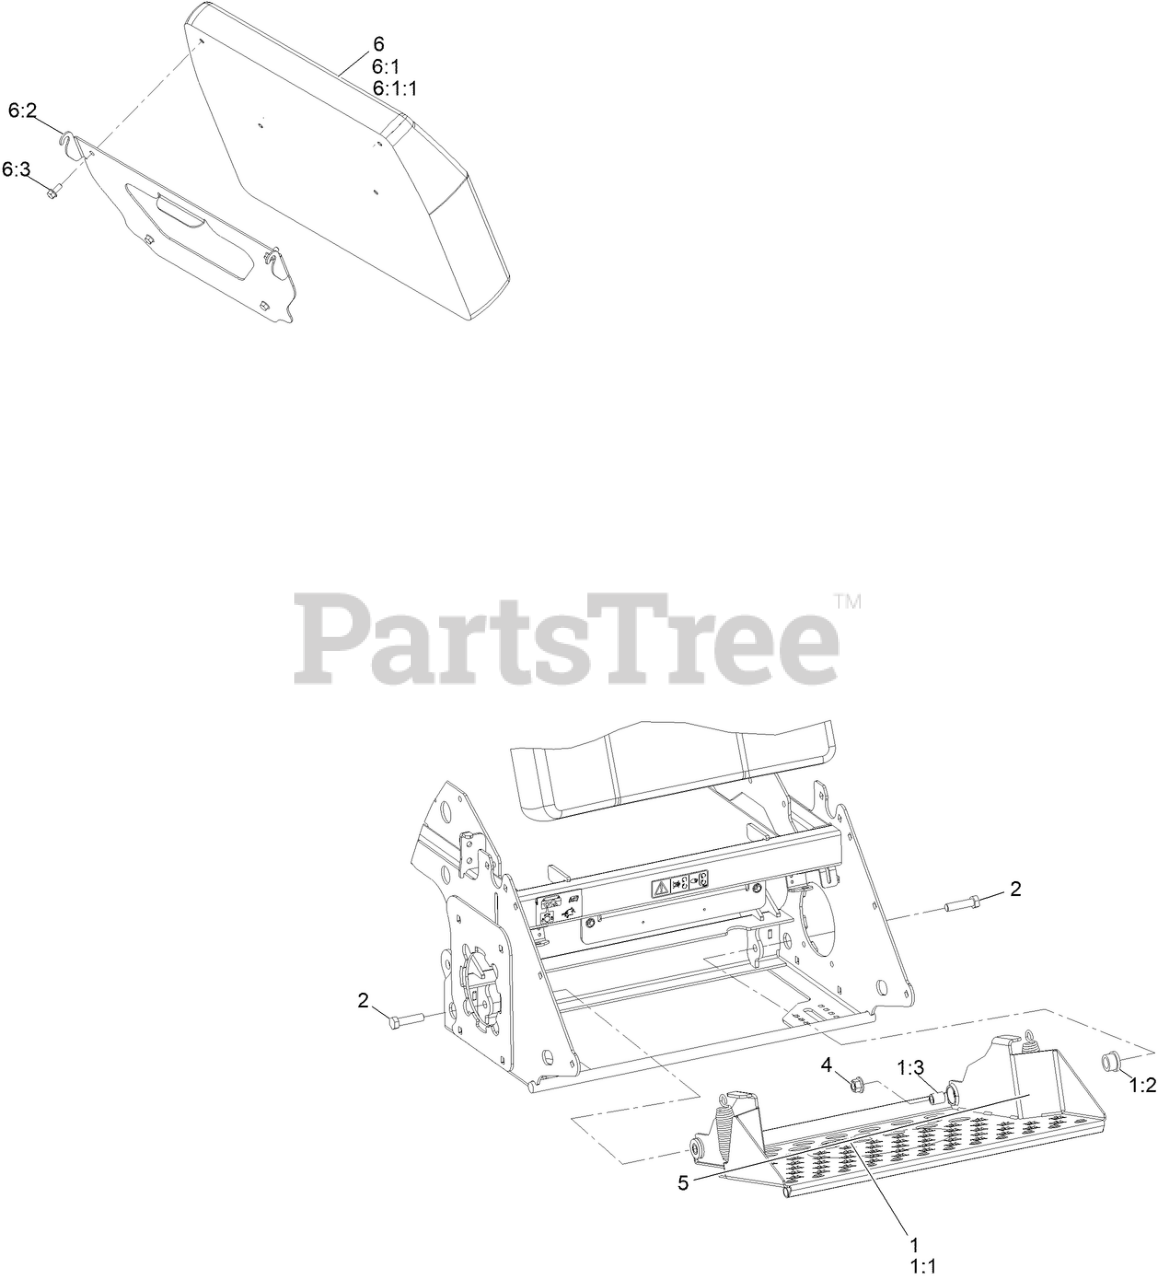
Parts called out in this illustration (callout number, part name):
1	ASM-OPERATORS PLATFORM
1:1	ASM-Operator Platform [black]
1:2	BUSHING-RUBBER
2	SCREW-HH
4	Nut-Lock 1/2-13
5	SPRING-EXTENSION
6	ASM-THIGH PAD
6:1	PAD-THIGH
6:1:1	COVER-PAD
6:2	PLATE-HINGE-THIGH PAD
6:3	SCREW-HHF
